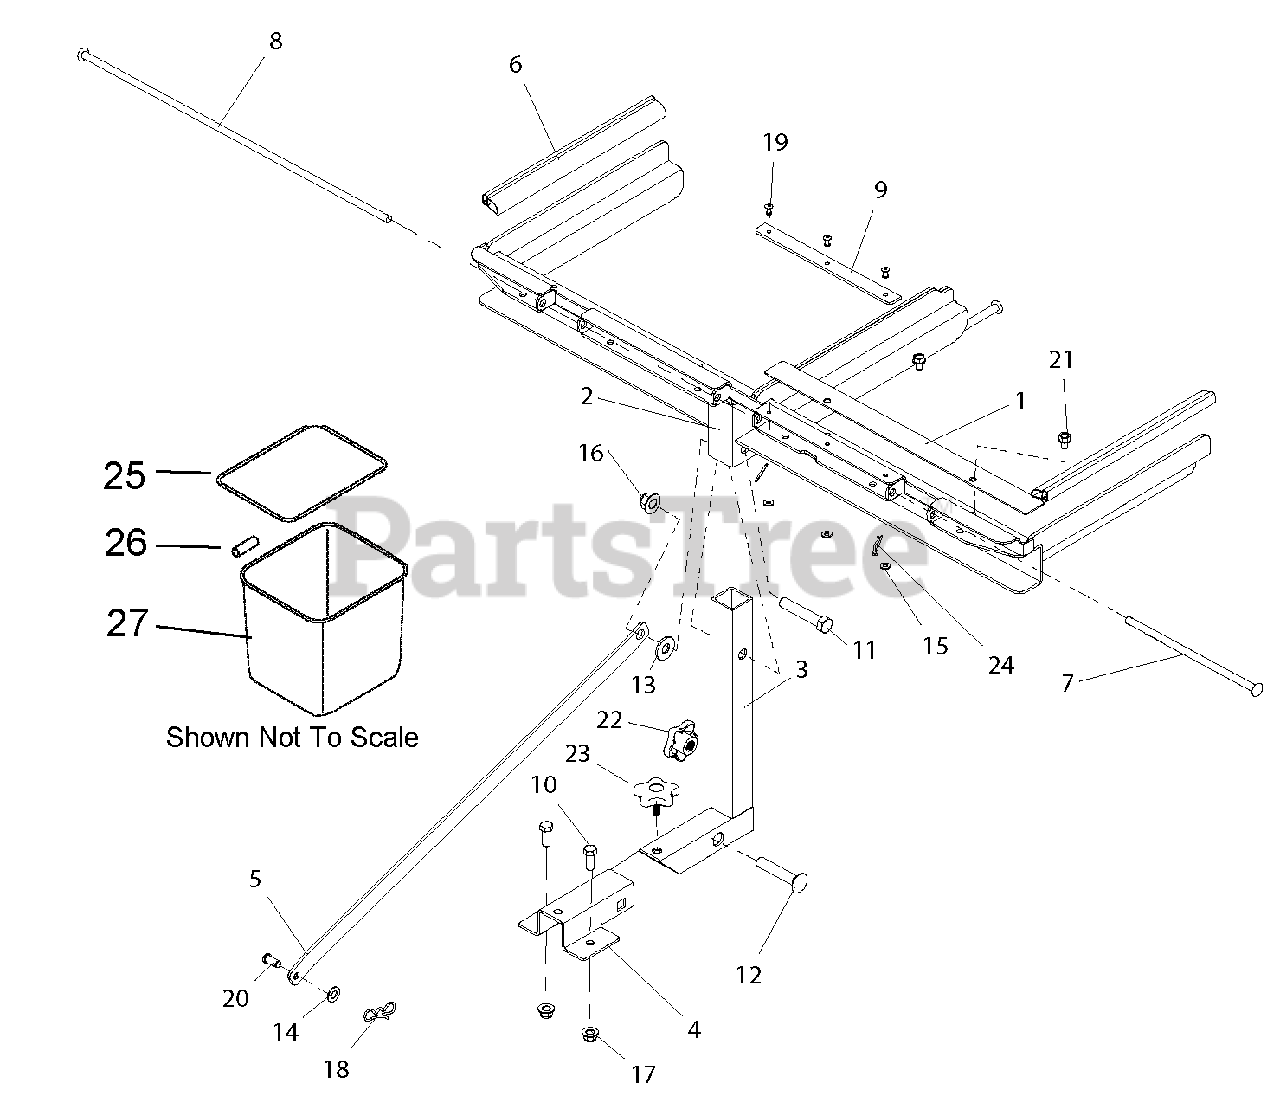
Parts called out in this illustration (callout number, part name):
1	BRKT-BAGGER OVERLAP
2	ASS'Y, BAGGER FRAME UPPER
3	BRKT, RECEIVER SLEEVE INSERT
4	BRKT, RECEIVER LOWER
5	BRKT, BAG FRAME SUPPORT BAR
6	SEAL, BULK
7	PIN, BAGGER HINGE (L)
8	PIN, BAGGER HINGE (R)
9	SEAL, HINGE
10	@BLT-HEX .38-16X1.00 GR5 YWZC
11	@BLT-HEX .50-13X2.75 GR5 YWZC
12	BLT-RDHDSQNK .50-13X2.75 G5YZ
13	WSHR-FL-STL .531X1.250X.10 YWZ
14	@WSHR-FL-STL.406X.812X.065 YWZ
15	@WSHR-FL-STL.219X.50X.049 YWZC
16	@NUT-LK-NYL-FLG .50-13 YWZC
17	@NUT-LK-NYL-FLG .38-16 YWZC
18	PIN,BOW TIE LOCKING .091X1.875
19	RVT-POP.187X.527 DOME ST
20	PIN-CLEV .38X.75 YWZC
21	@SCR-TAP .31-18X.50 HWH TR YWZ
22	KNOB, WING
23	KNOB, WING STUDDED
24	PIN-HAIR, ENDRIES #25 YWZC
25	FRAME, ZOOM BAG
26	HOSE, .38 X.50 X 3.00 VINYL
27	BAG, MESH ZOOM
